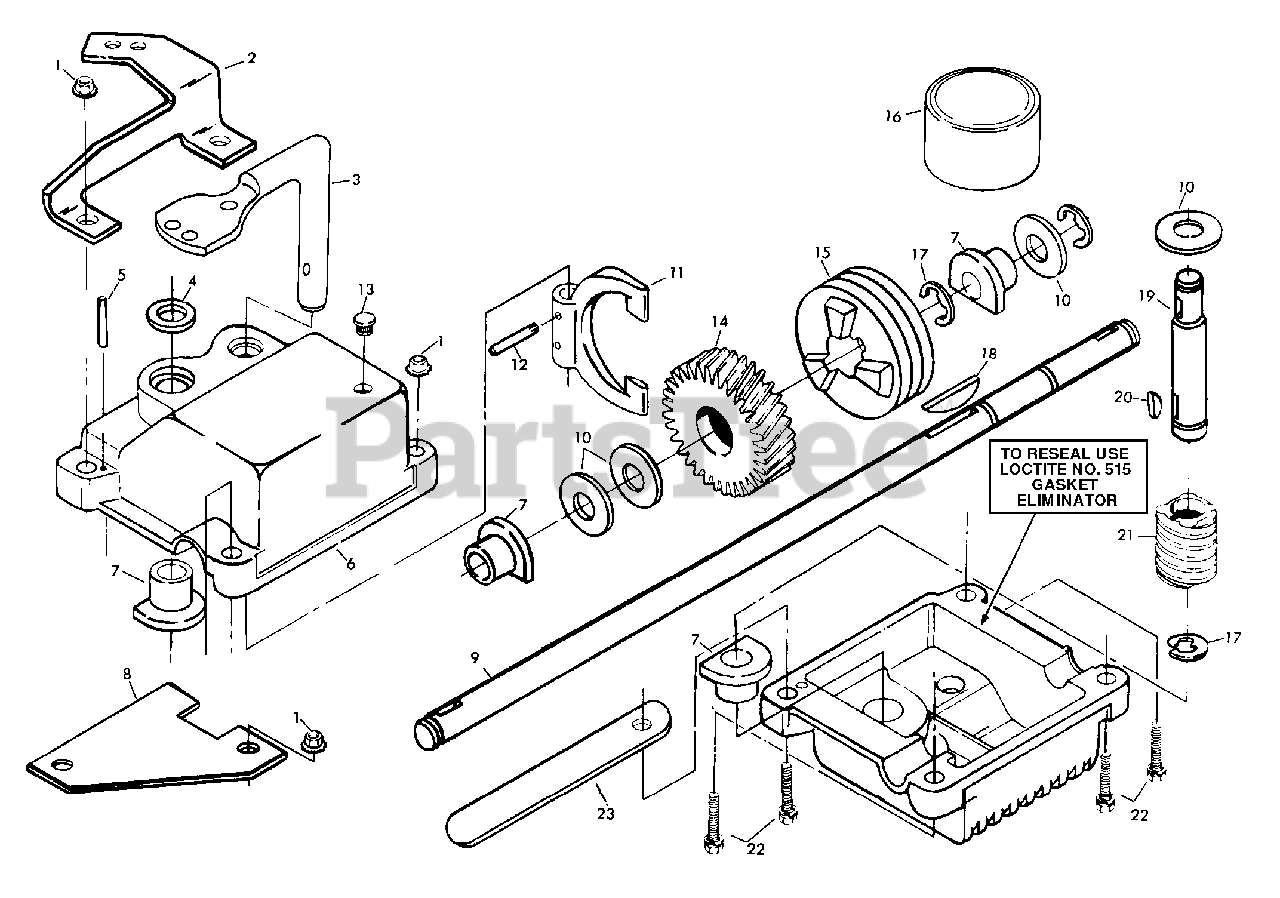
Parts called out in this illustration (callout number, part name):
1	Keps Locknut 1/4-20
2	Adjusting Bracket
3	Shifter Assembly
5	Grooved Pin 1/8 x 1/2
6	Gear Case Halves
8	Spring Bracket
9	Drive Shaft
10	Hardened Washer
11	Yoke Clutch
12	Grooved Pin 1/8 x 3/4
14	Helical Gear
15	Jaw Clutch
16	Grease
17	E-Ring
18	Hi-Pro Key
19	Worm Shaft
20	Woodruff Key #3
21	Worm
22	Hex Head Machine Screw 1/4-20 x 1-1/4
23	Identification Tag
